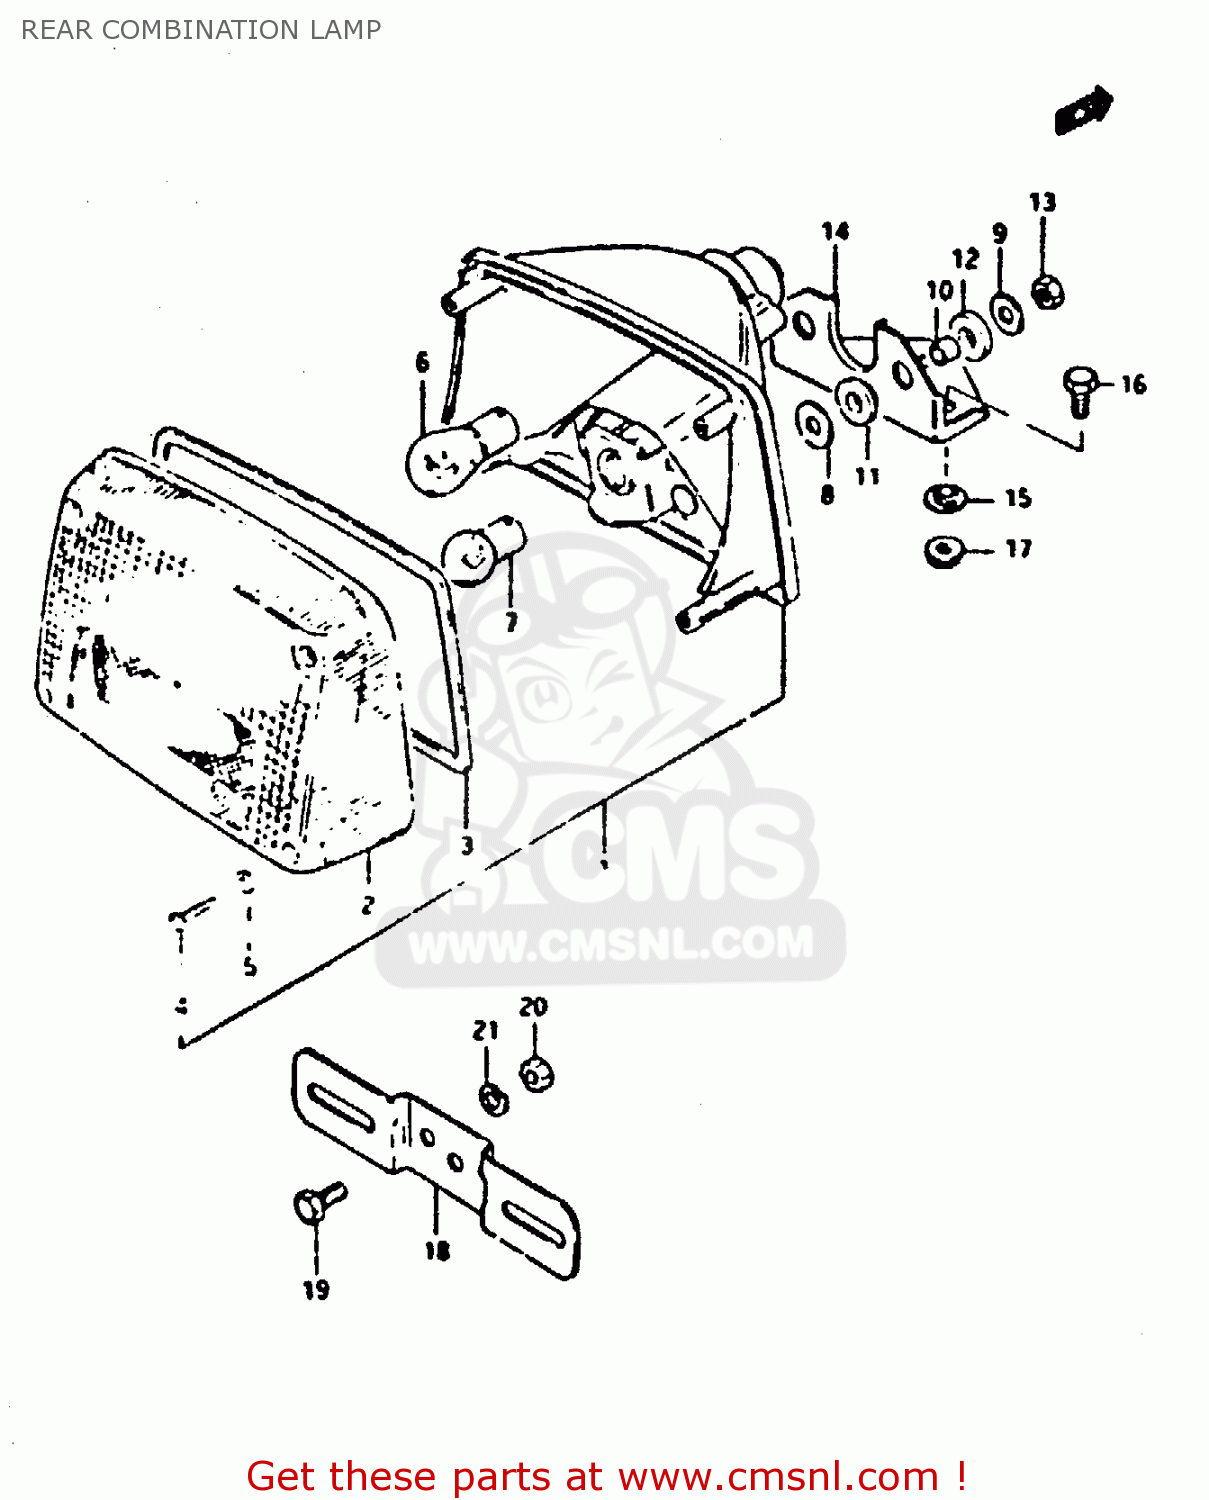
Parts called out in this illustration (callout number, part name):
1	LAMP ASSEMBLY,REAR COMBINATION
2	LENS
3	GASKET (NAS)
4	SCREW,REAR COMBINATION LAMP
5	GASKET (NAS)
6	BULB(12V23W)
7	BULB
8	WASHER
9	WASHER(6,5X22X1.6)
10	SPACER(6.1X9X7.5)
11	CUSHION
12	CUSHION
13	NUT 6MM
14	BRACKET,RR COMBINATION LAMP
15	WASHER
16	BOLT, UPPER
17	NUT 6MM
18	BRACKET, LICENSE PLATE
19	BOLT,REAR
20	NUT
21	LOCK WASHER
